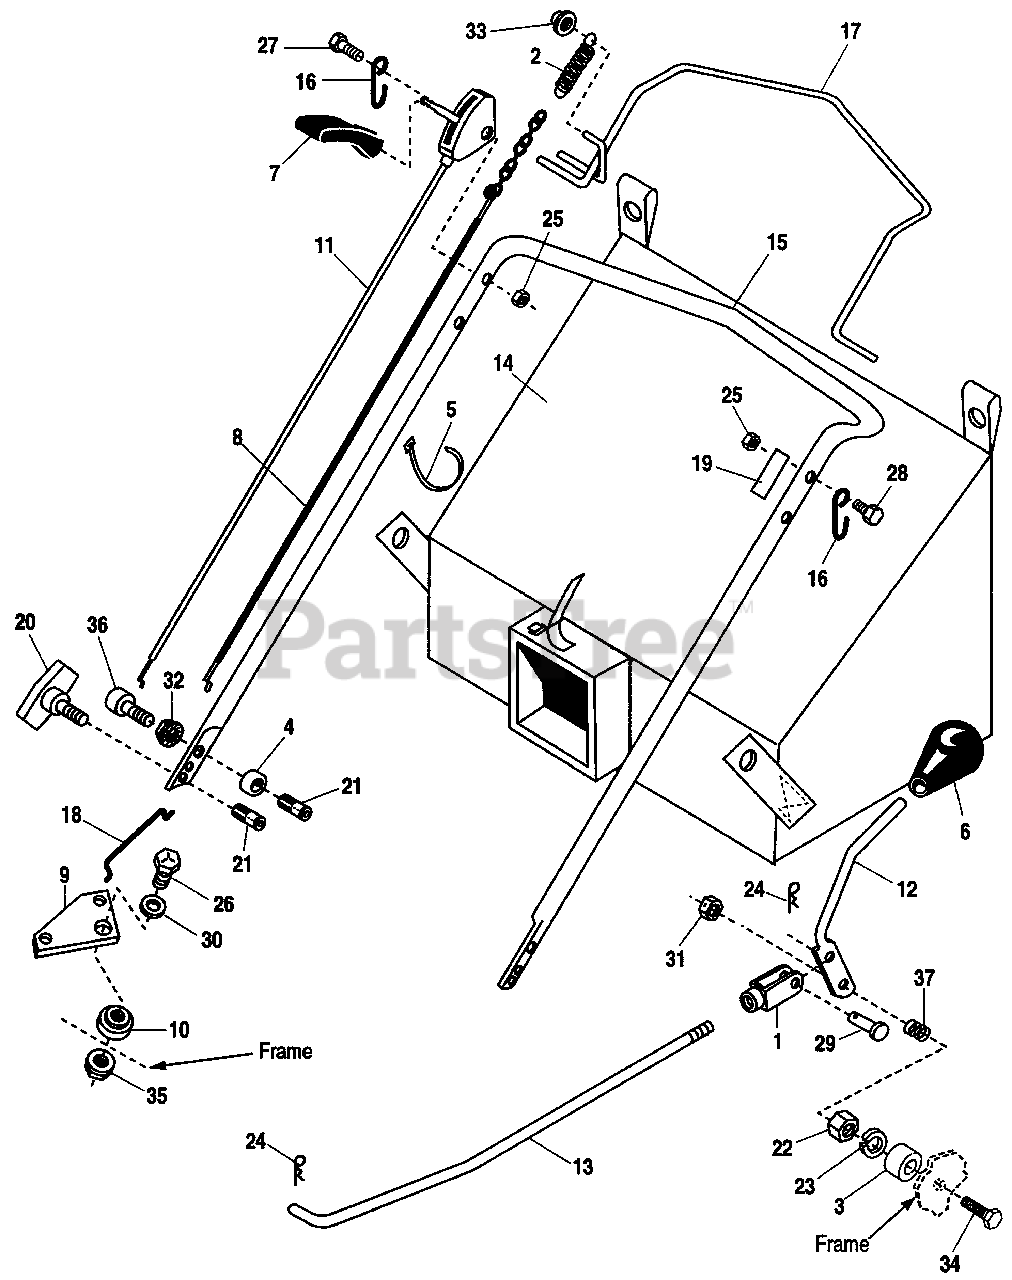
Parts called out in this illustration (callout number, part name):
5	TIE, Self-locking
6	KNOB, Handle, Height Adjustment
7	HANDLE, Shift Control
8	CABLE, Traction
10	SPACER, Pivot
11	CABLE, Shift Control
12	HANDLE, Height Adjustment
18	LINK, Traction
19	DECAL, Clutch Bail
20	KNOB, Handle
21	INSERT, Threaded, 5/16-18 (Installed in frame)
22	NUT, Hex 3/8-16
23	LOCKWASHER, 3/8
24	PIN, Quick
25	NUT, Hex, Nylock, 1/4-20
26	CAPSCREW, Hex Hd., 5/16-18 x 1
27	CAPSCREW, Hex Hd., 1/4-20 x 2
28	CAPSCREW, Hex Hd., 1/4-20 x 1-1/2
30	WASHER, 5/16
31	NUT, Flange Center Lock, 3/8-16
32	NUT, Serrated, Flange, 5/16-18
33	PUSH NUT, Pal, 5/16
34	CAPSCREW, 3/8-16 x 2-1/2
35	NUT, Hex, Flange Lock, 5/16-18
36	CAPSCREW, Hex, Socket Hd., 5/16-18 x 1-3/4
